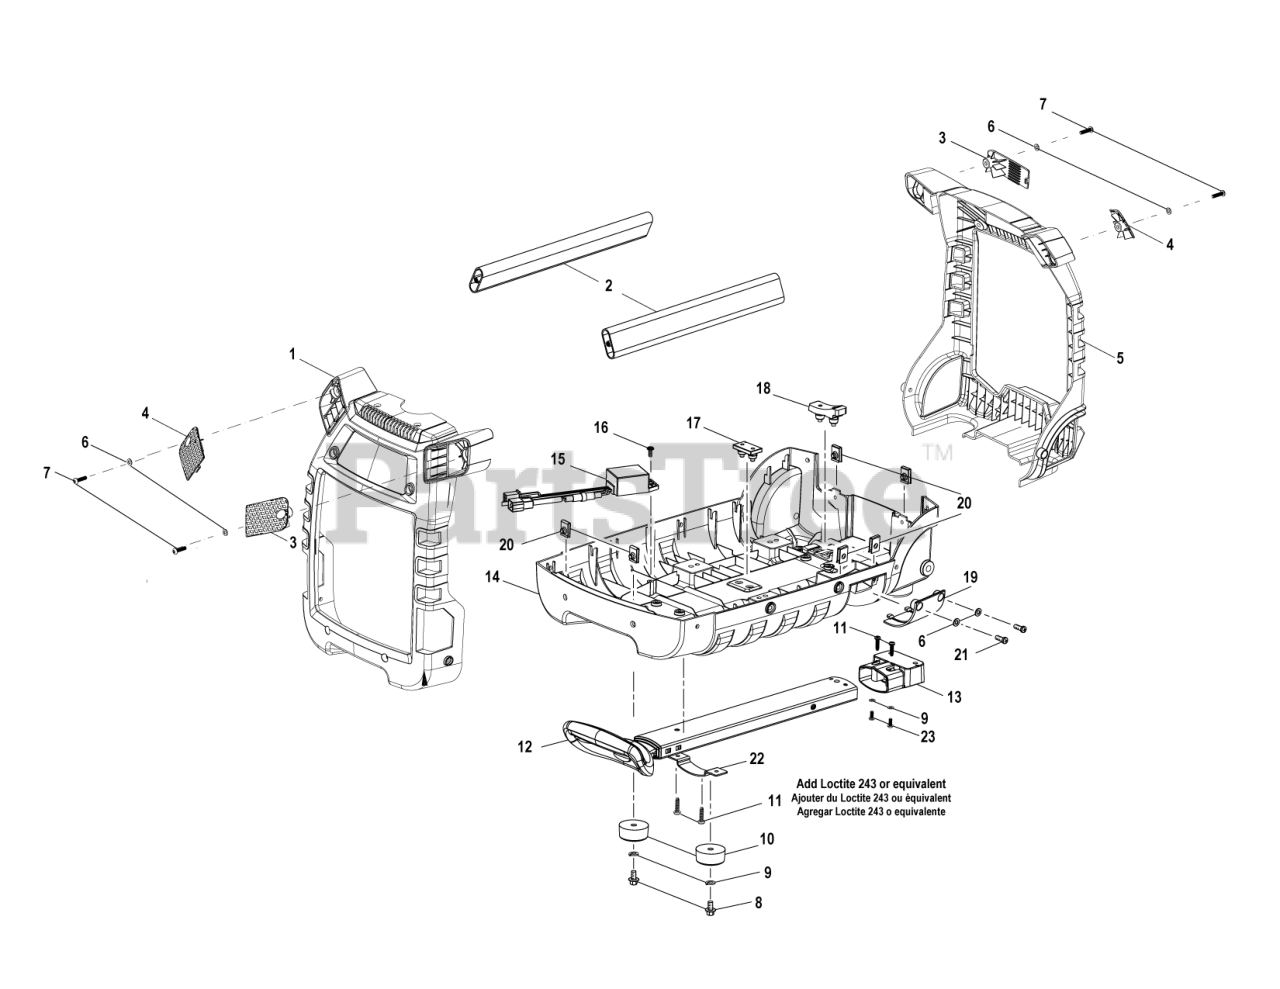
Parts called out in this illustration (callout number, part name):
1	COVER, FRONT
2	BAR, ALUMINUM SIDE
3	CAP, HANDLE (RIGHT)
4	CAP, HANDLE (LEFT)
5	COVER, BACK
9	WASHER, LOCK
10	FOOT, ISOLATOR
12	ASSY., HANDLE
13	BRACKET, RETRACTABLE HANDLE
14	ASSY., BOTTOM BASE
15	REGULATOR (AC TO DC)
17	ISOLATOR, ENGINE (FRONT)
18	ISOLATOR, ENGINE (BACK)
19	DOOR, OIL DRAIN
22	BRACKET, RETRACTABLE HANDLE
